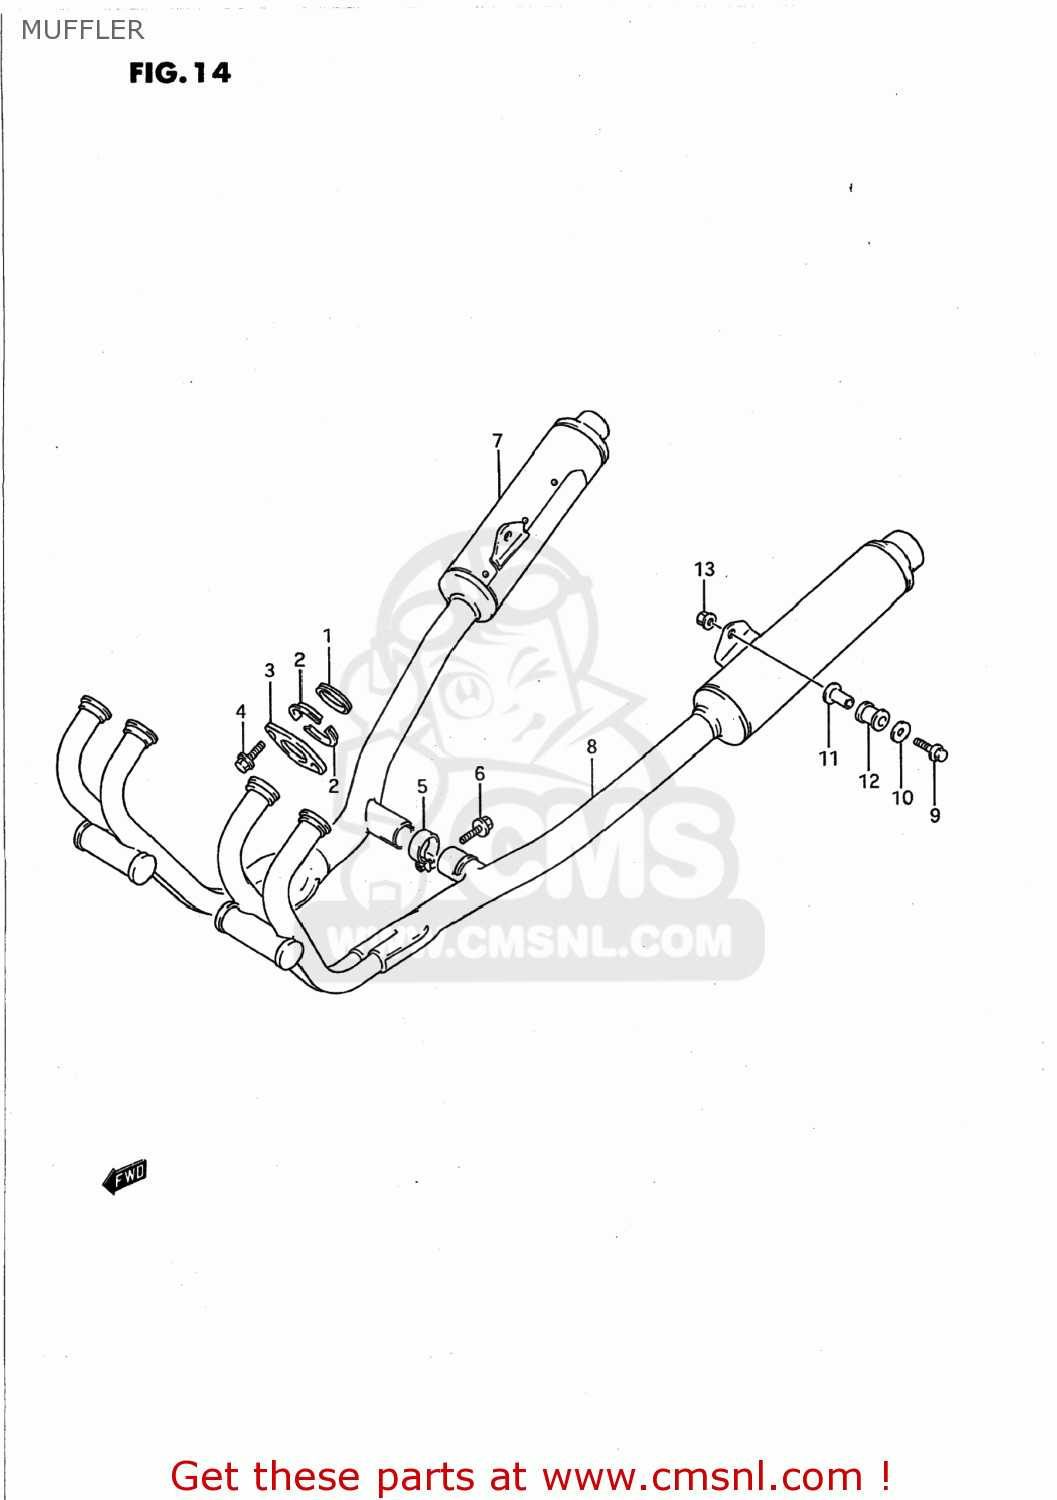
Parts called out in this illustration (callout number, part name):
1	GASKET,EXHAUST (NAS)
2	PLATE,EXHAUST PIPE
3	CLAMP,EXHAUST PIPE
4	BOLT
5	CLAMP,MUFFLER CONNECTOR
6	BOLT
7	MUFFLER ASSEMBLY
8	MUFFLER ASSEMBLY
9	BOLT(8X40)
10	WASHER (8.1X33X1.6)
11	SPACER(8.6X12X27.1)
12	CUSHION
13	NUT
